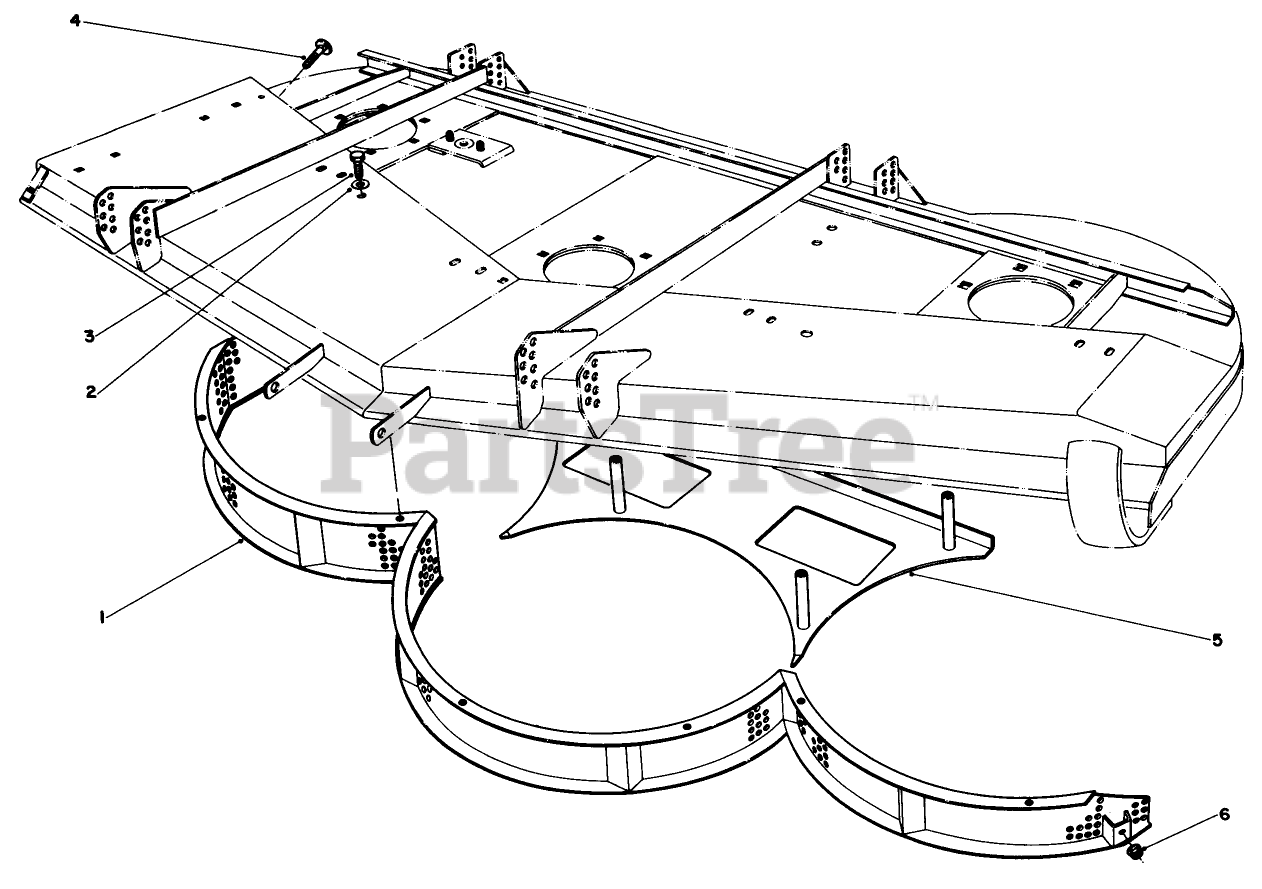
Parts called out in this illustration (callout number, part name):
2	WASHER-LOCK
3	SCREW-HH
4	BOLT-CARR
6	NUT-HHF, WHIZ
